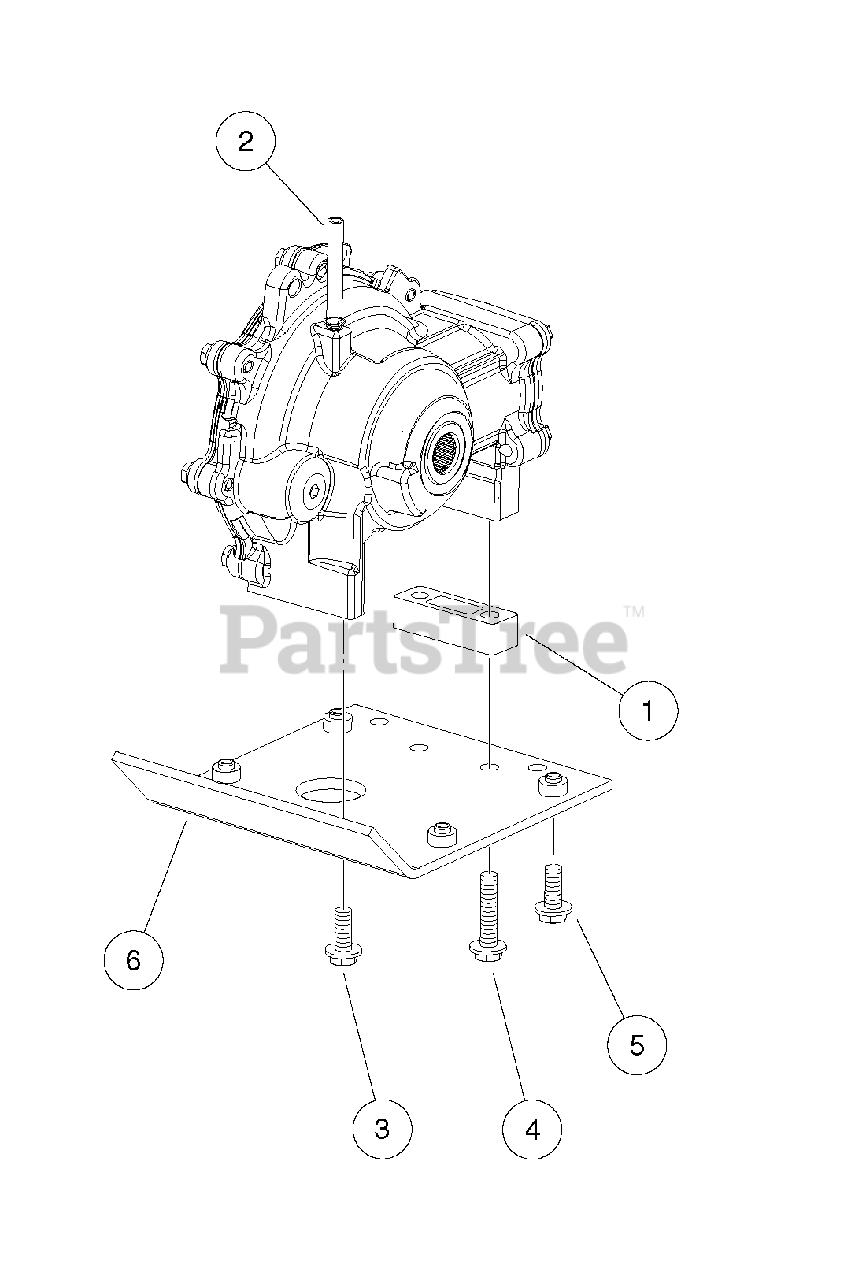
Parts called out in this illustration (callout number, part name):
1	Spacer Block, Diff
2	Hose, Vent, Front Diff
3	Bolt Flanged Head, 3/8-16x1.0 with Loctite
4	Bolt Flanged Head, 3/8-16x1.500 with Loctite
5	Bolt, Flange Head, M10 X 1.5 X 25
6	Asm, Mount, Diff Plate
